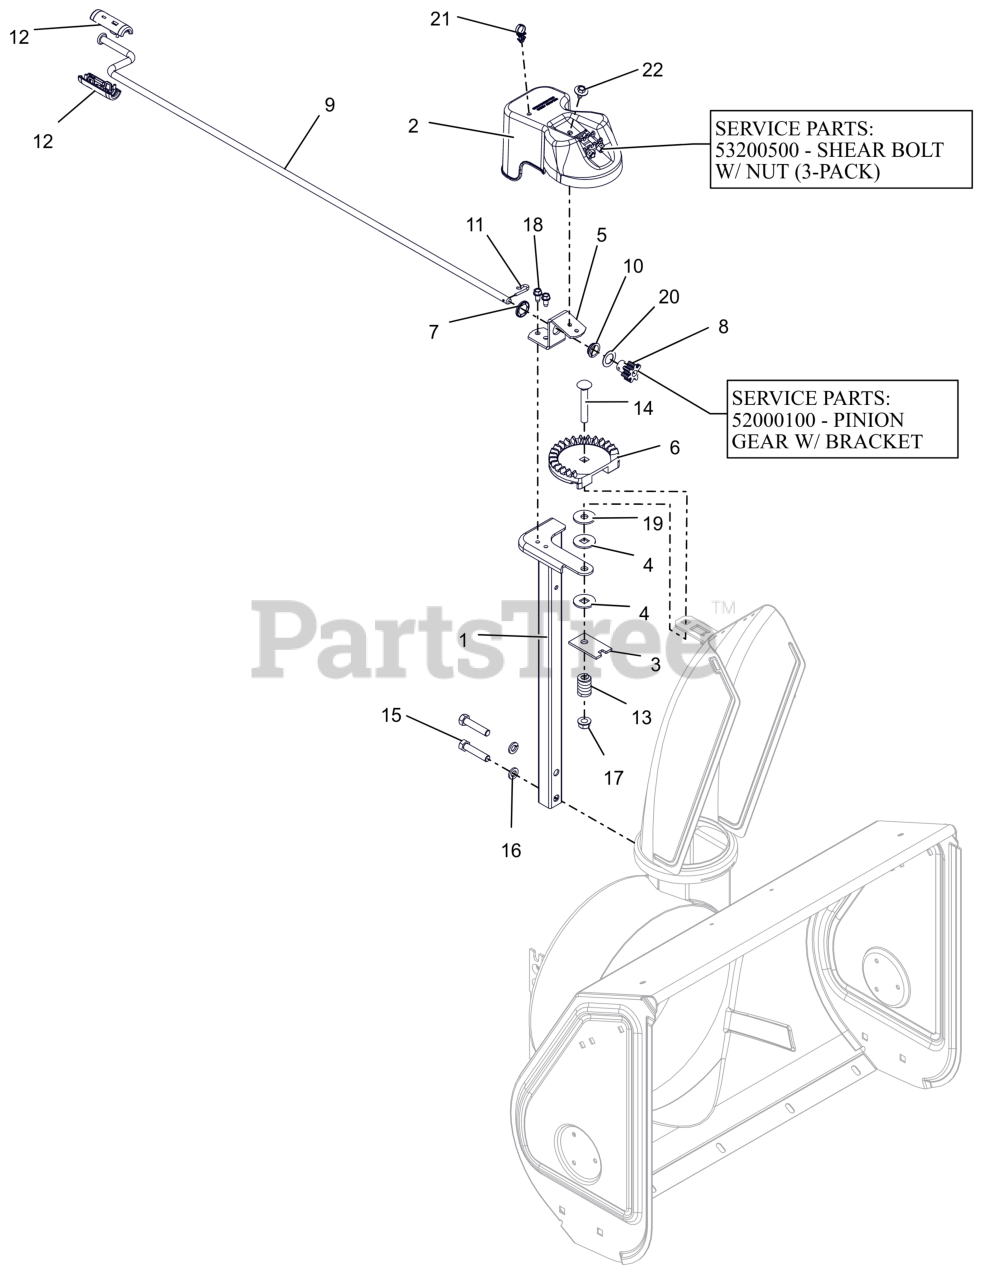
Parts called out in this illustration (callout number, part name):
1	CHUTE PEDESTAL, TALL COMPACT
2	GEAR COVER ASSY SM SHEAR BOLT
2	SHEAR BOLT WITH NUT
3	PLATE, FRICTION
4	FRICTION WASHER
5	BRACKET, PINION GEAR
6	CHUTE GEAR
7	PUSHNUT .625
8	PINION GEAR - CHUTE
8	PINION GEAR W/BRACKET
9	ROD, CHUTE CRANK, COMP&SNOTEK
10	BUSHING, POLYLINER-.63 SNAPIN
11	PIN, SPRING CLIP
12	KNOB,CRANK-SNAP COMPACT-GRAY
13	SG-COMP .187X.56X1.62
14	BLT,RHSN .38-16X2.50 G5 ZCC
15	BLT, HEX .38-16X1.75 G5 ZCC
16	WSHR,LK-REG .375X.094 ZCC
17	NUT-LK-TOP-FLG .38-16 ZC120
18	SCR-TAP .25-20X.50 HWH ZCC
19	WSHR FL STL .406X1.25X.10ZC120
20	WSHR-THRST .625 X 1.0 X .03
21	CLIP, CABLE GUIDE
22	SCR, TAP .25-20X.50 LG HWH ZCC
